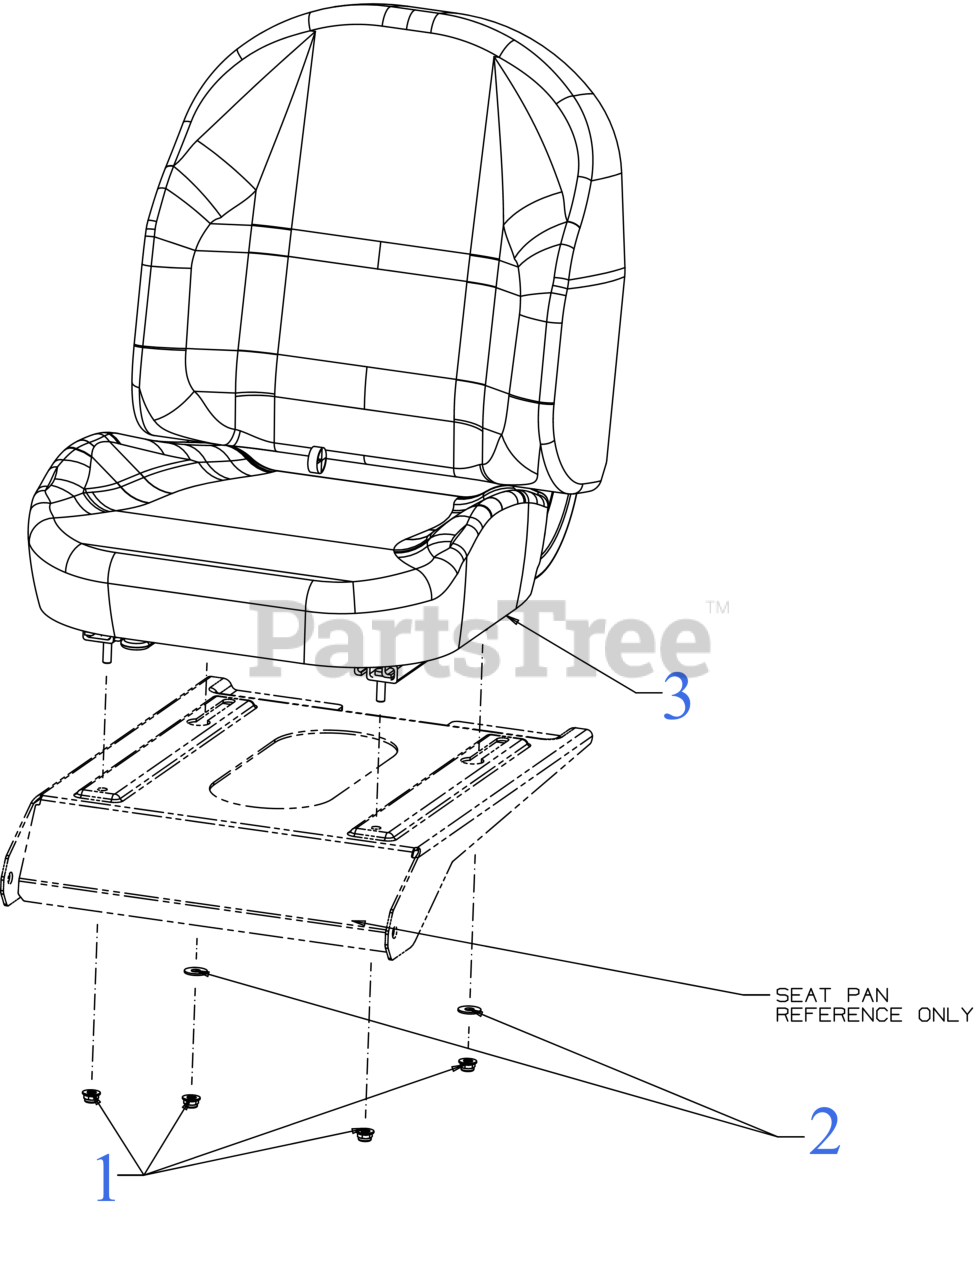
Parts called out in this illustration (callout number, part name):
1	FLANGE LOCK NUT 5/16-18
2	FLAT WASHER
3	SEAT (CUB/ELECTRIC SLIDE)
